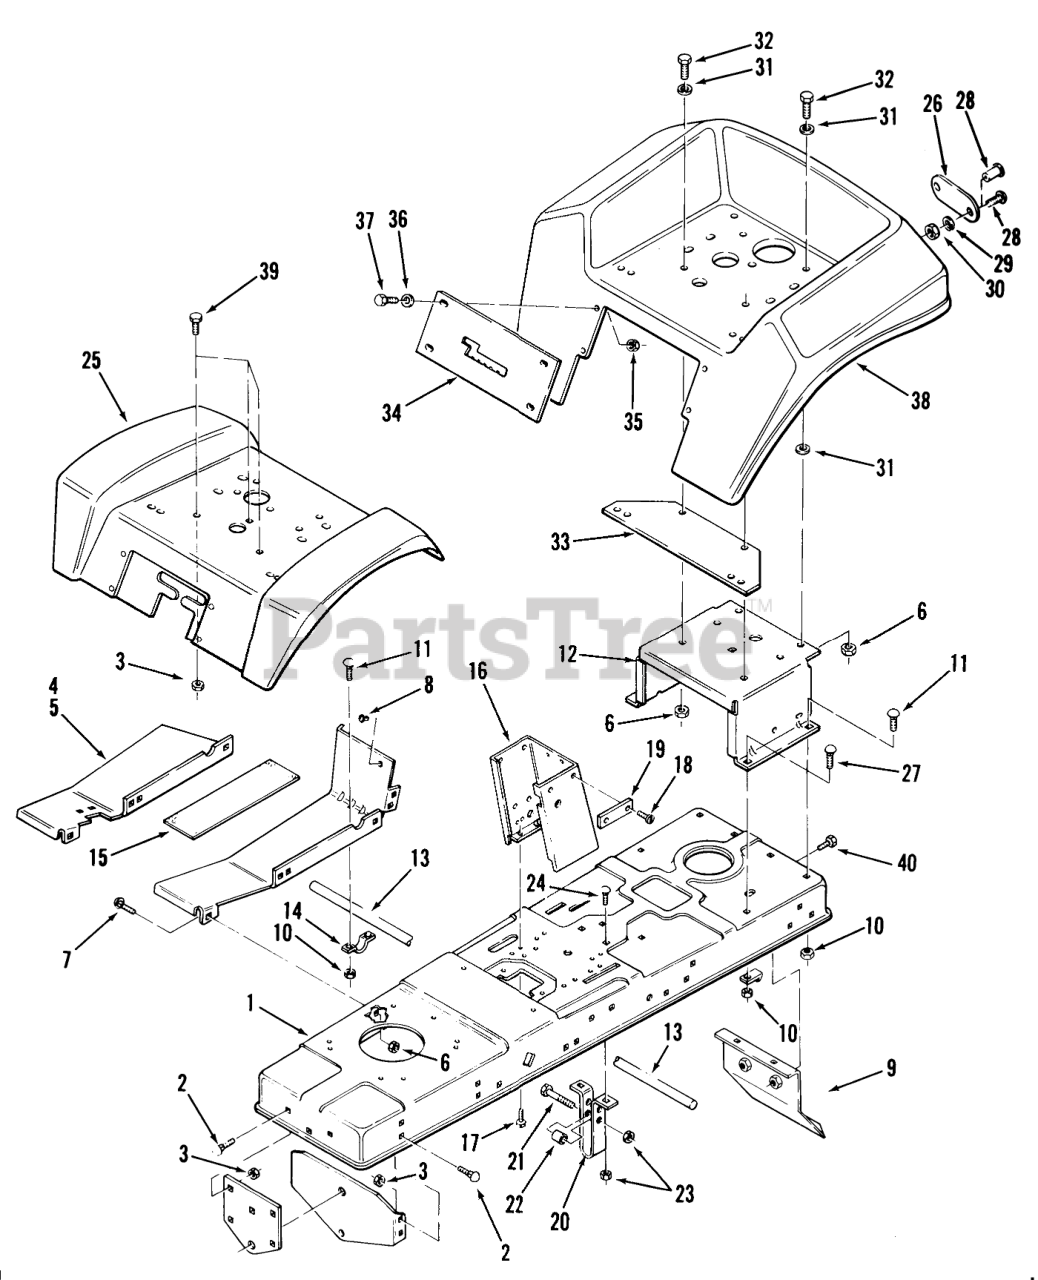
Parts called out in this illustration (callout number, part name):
1	Frame
2	CARRIAGE BOLT -4
3	Nut
4	Footrest RH
5	Footrest LH
6	Nut
7	CARRIAGE BOLT -4
8	BUMPER-RUBBER
9	Hitch Drawbar
10	Nut
11	CARRIAGE BOLT -4
12	SUPPORT-SEAT R
13	SHAFT-REAR
13	Shaft-Rear
14	CLAMP
15	PAD-FOOTREST
16	ASSY-HOODSTAND
17	SCREW
18	HEX WASH HD SCREW
19	Spacer
20	Guide-Mower
21	Bolt
22	SPACER
23	Nut
24	Bolt-Carriage
25	Assy-Fender & Plate
26	Reflector
27	CARRIAGE BOLT -4
27	Bolt
28	Screw
28	Poprivet
29	Lockwasher
30	Nut
31	WASHER
32	Bolt
33	Seat Plate
34	Shift Plate
35	Nut
37	Screw
38	Fender
39	H H C S
40	Bolt
